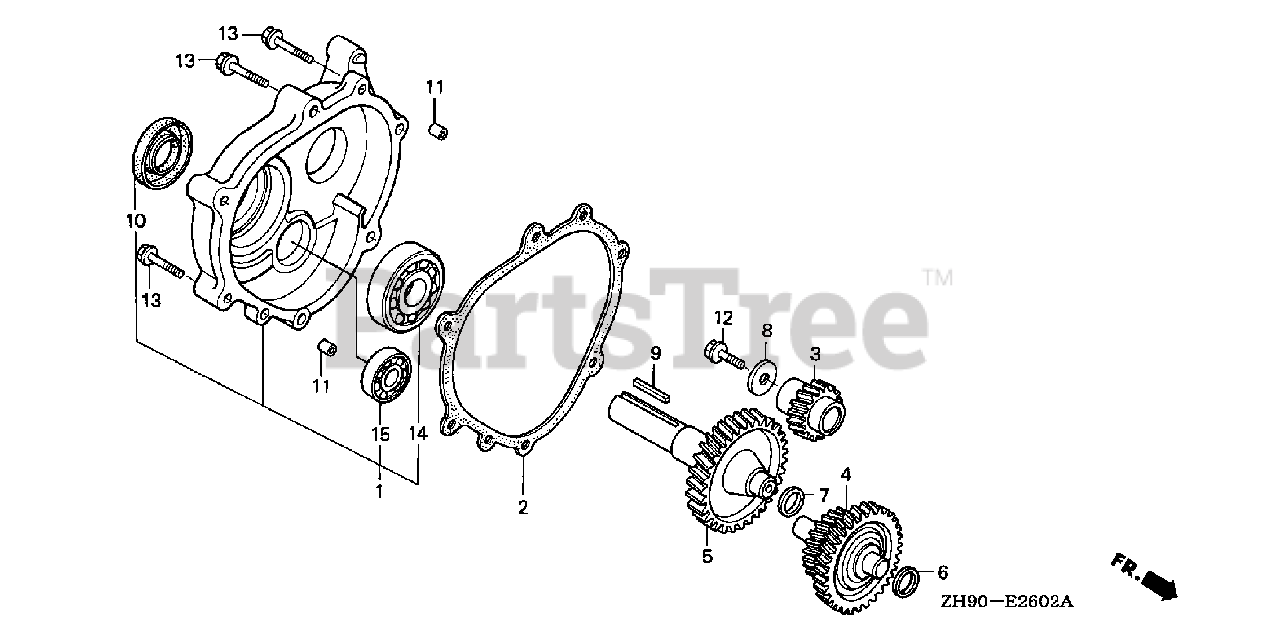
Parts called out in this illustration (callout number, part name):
1	COVER ASSY., REDUCTION CASE
2	GASKET, CHAIN CASE COVER
3	GEAR, PRIMARY DRIVE (17T)
4	COUNTERSHAFT
5	SHAFT, P.T.O. (H-TYPE)
6	SHIM A
7	SHIM B
8	WASHER (8MM)
9	KEY (6.3X6.3X63)
10	OIL SEAL (30X46X8)
11	PIN A, DOWEL (8X14)
12	BOLT, FLANGE (8X25)
13	BOLT, FLANGE (8X40)
14	BEARING, RADIAL BALL (6204)
15	BEARING, RADIAL BALL (6302)
